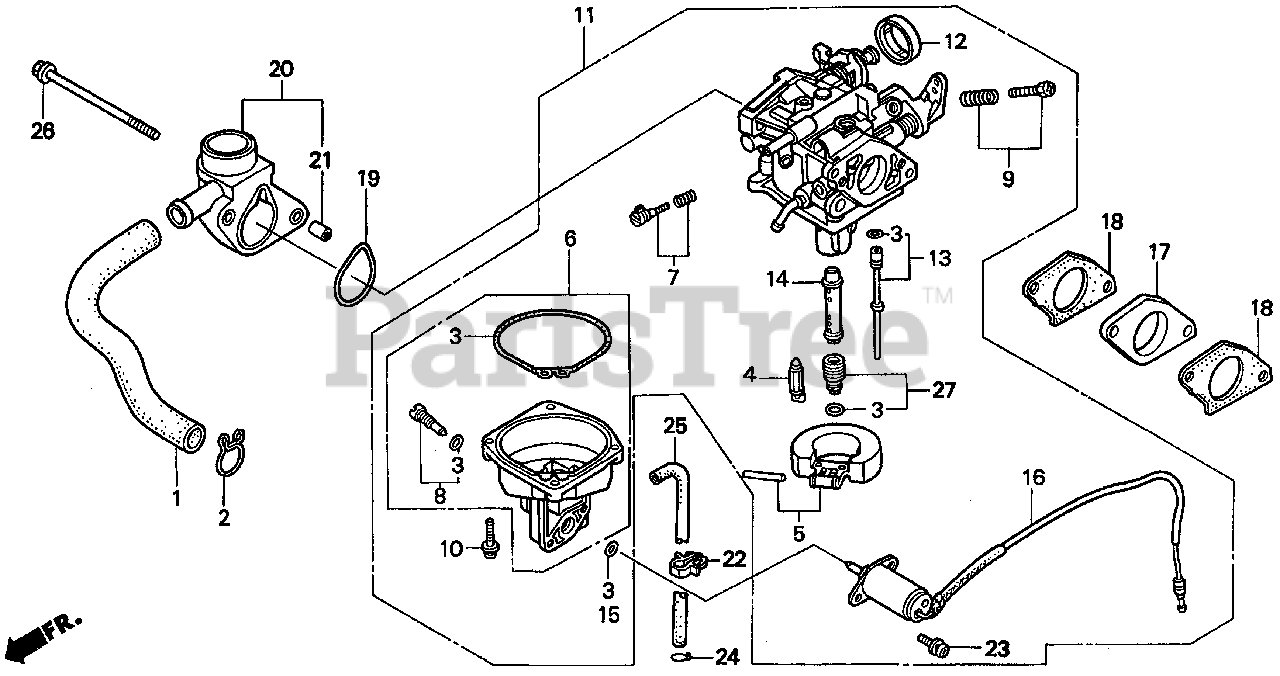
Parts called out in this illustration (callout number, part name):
1	TUBE, BREATHER
2	CLIP, BREATHER TUBE
3	GASKET SET
4	VALVE SET, FLOAT
5	FLOAT SET
6	CHAMBER SET, FLOAT
7	SCREW SET
8	SCREW SET, DRAIN
9	SCREW SET
10	SCREW-WASHER
11	CARBURETOR ASSY. (BG21A A/B)
11	CARBURETOR ASSY.
12	CAP, CHOKE LEVER DUST
13	JET SET (#50)
14	NOZZLE, MAIN
15	O-RING (5.8X1.9)
16	VALVE ASSY., SOLENOID
17	INSULATOR, CARBURETOR
18	GASKET, CARBURETOR
19	GASKET, AIR CLEANER
20	ELBOW, AIR CLEANER
21	COLLAR, DISTANCE
22	CLIP B, CABLE
23	SCREW-WASHER (5X12)
24	CLIP, TUBE (B8)
25	BULK HOSE, VACUUM (4.5X1000) (4.5X460) (BULK HOSE 95005-45008-10M)
26	BOLT, FLANGE (6X105)
27	JET SET, MAIN (#82)
27	JET SET, MAIN (#85)
27	JET SET, MAIN (#88)
